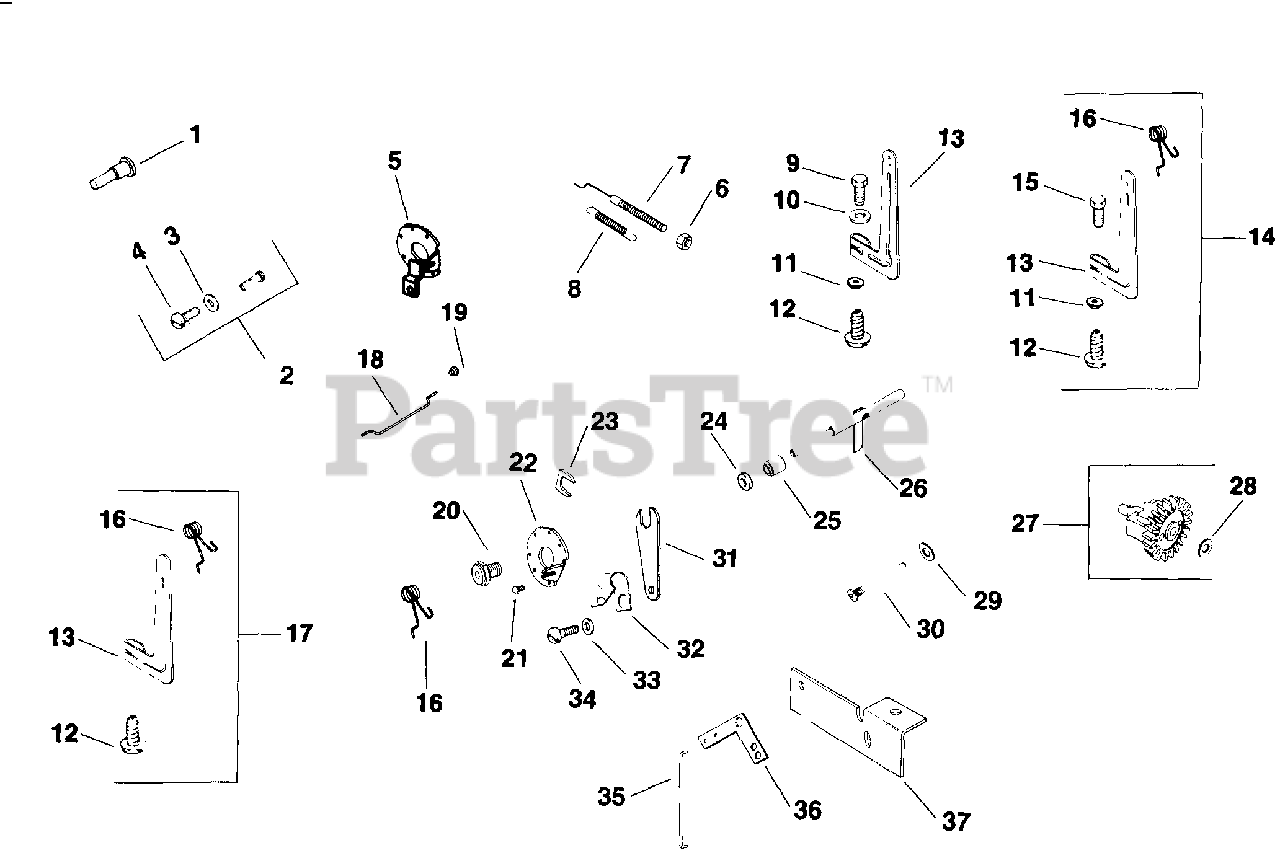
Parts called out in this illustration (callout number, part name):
7	ARM - DISCONTINUED
13	LEVER, GOVERNOR - DISCONTINUED
18	LINKAGE
20	BUSHING - (#DSC)
22	DISC, GOVERNOR REGULATING
26	KIT,SHAFT
27	KIT, GOVERNOR GEAR
30	PIN
31	BRACKET - DISCONTINUED
